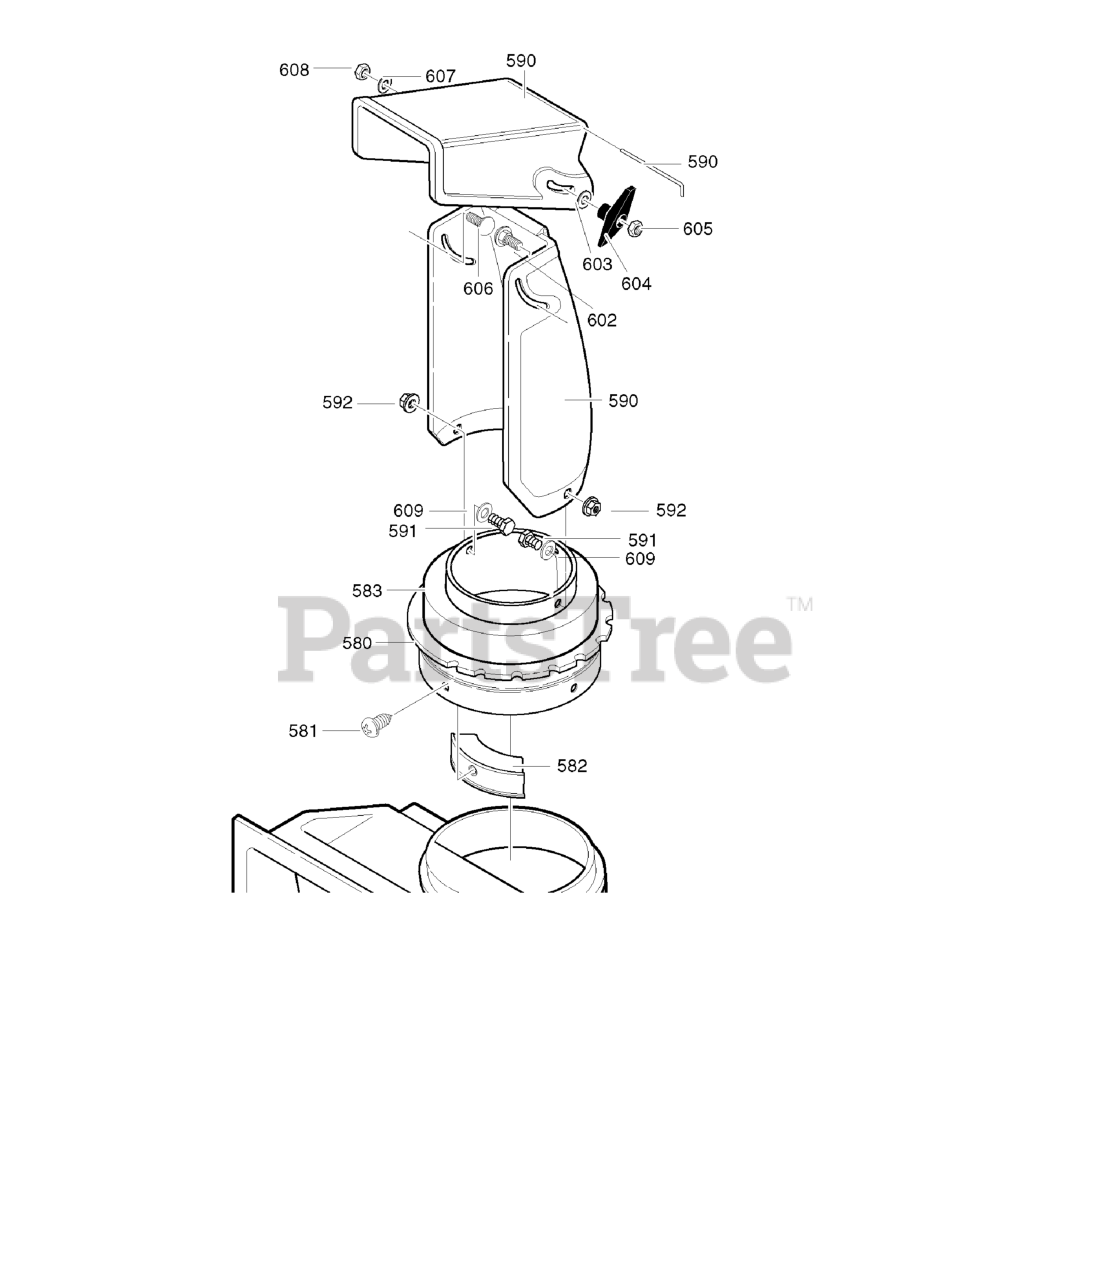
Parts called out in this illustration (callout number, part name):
580	RING, CHUTE
581	SCREW, #10 X .50
582	GUIDE, CHUTE
583	DONUT FOAM
590	CHUTE DEFLECTOR, LOWER
591	SCREW 1/4-20 X .50
592	NUT, 1/4-20
600	CHUTE DEFLECTOR, UPPER
602	BOLT, 5/16-18 X 1.25 CARRIAGE
603	WASHER, FLAT
604	KNOB, T
605	NUT, 5/16-18
606	SCREW, 5/16-18 x 0.75
607	WASHER, FLAT .349 X .69 X .066
608	NUT, 5/16-18
609	WASHER, FLAT
